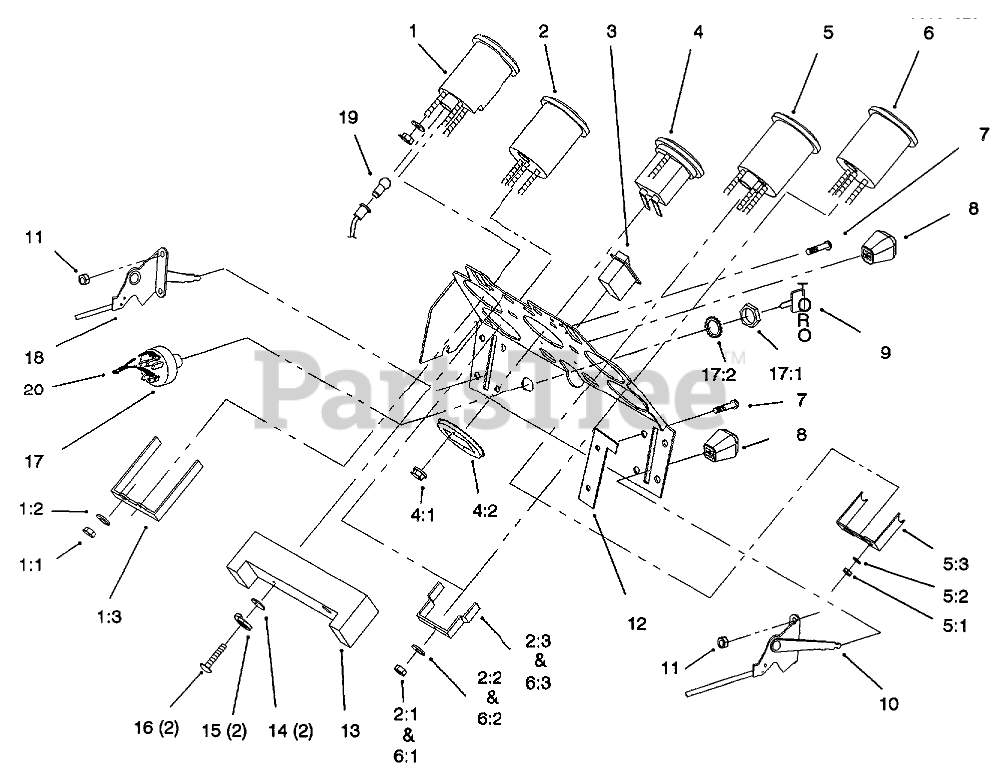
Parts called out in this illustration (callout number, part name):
1	TACHOMETER
1:1	NUT-HEX
1:2	WASHER-LOCK
1:3	BRACKET - GAUGE MOUNT
2	FUEL-GAUGE
2:1	NUT-HEX
2:2	WASHER-LOCK
2:3	CLAMP-MOUNTING
3	SWITCH-HEADLIGHT
4	Hourmeter
4:1	NUT-HEX, KEPS
4:2	Retainer
5	VACUUM-GAGE
5:1	NUT-HEX
5:2	WASHER-LOCK
5:3	Bracket-Mounting
6	Voltmeter
6:1	NUT-HEX
6:2	WASHER-LOCK
6:3	CLAMP-MOUNTING
7	SCRW-PHC
9	KEY-IGNITION
10	CONTROL-CHOKE
11	Nut
12	Stop-Choke
13	CIRCUIT-BRD 8 LIGHT
14	WASHER-FLAT
15	WASHER-LOCK
16	Screw
17	IGNITION SWITCH ASM
17:2	WASHER-LOCK
18	CONTROL-THROTTLE
19	LAMP-MINIATURE GE 53X
